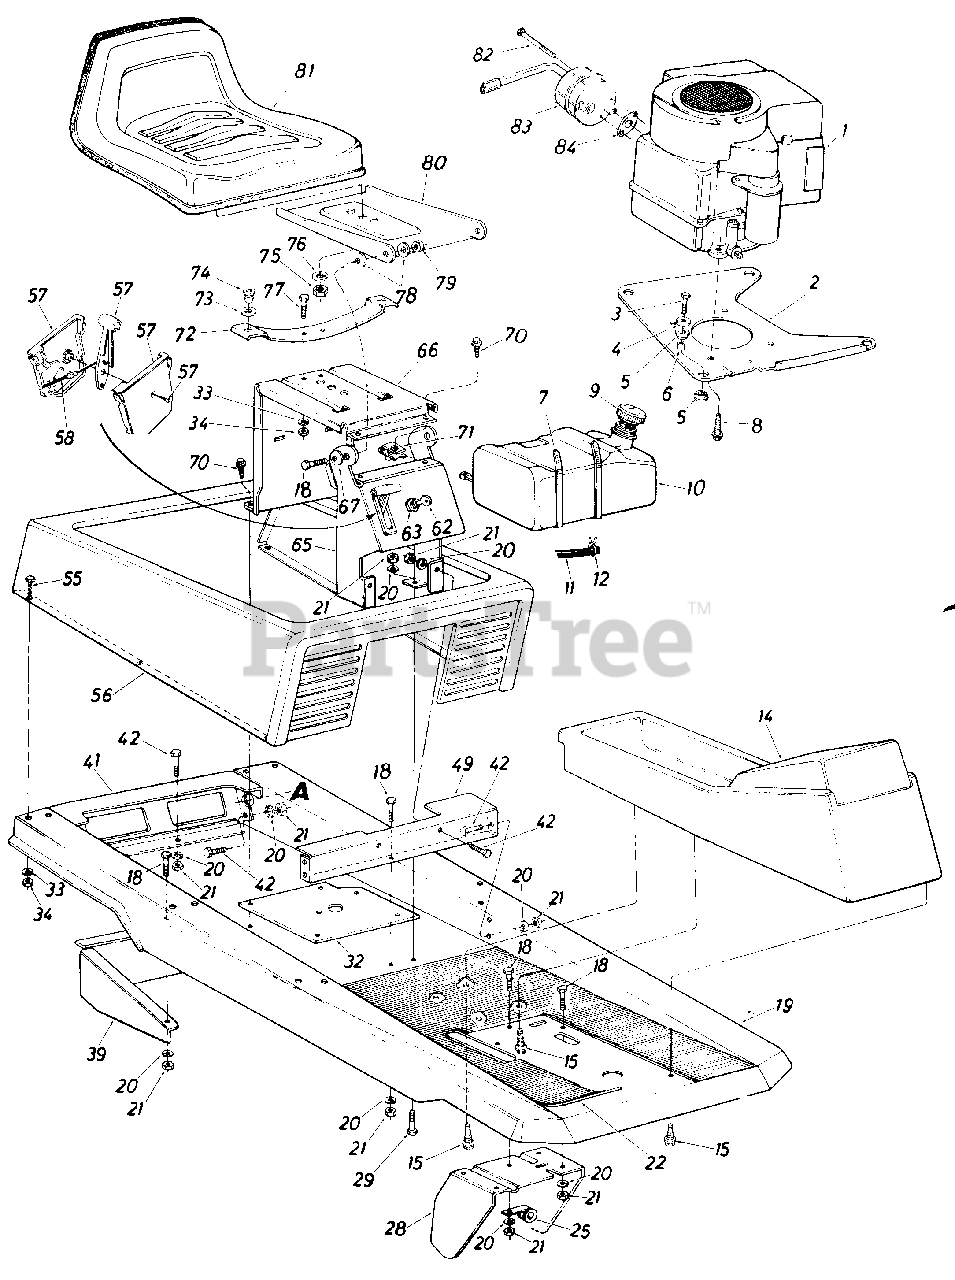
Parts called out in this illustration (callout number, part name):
1	Engine
2	Engine Mounting Plate
3	Hex Bolt 5/16-24 x 1.25" Lg.
4	Fl-Wash. .330" I.D. x 1.125" O.D.
5	Engine Mounting Grommet
6	Spacer.315" I.D. x .50" O.D. x .520" Lg.
7	Cable Tie
8	Hex Wash. Hd. Self-Tap Scr. 3/8-16 x 1.25" Lg.
9	Gas Gauge
10	Fuel Tank
11	Gas Line
12	Hose Clamp .406" Dia.
14	Front Console
15	Plastite Scr. 5/16" x 1.25" Lg.
18	Hex Bolt 5/16-18 x .75" Lg.*
19	Main Frame
20	L-Wash. 5/16" I.D.
21	Hex Nut 5/16-18 Thd.
22	Floor Mat
25	Clamp
28	Clutch-Brake Pedal Ass'y.
29	Hex Bolt 5/16-18 x .62" Lg
32	Mounting Brk't. Variable Speed Pulley
33	L-Wash. 1/4" I.D.
34	Hex Nut 1/4-20 Thd.
49	Seat Support & Frame Brk't.
55	Hex Bolt 1/4-20 x .50" Lg.
56	Engine Cover Ass'y.
57	Throttle Control Box Ass'y.
58	Throttle Control Wire
62	Ignition Key
63	Ignition Switch
65	Front Seat Bracket
66	Rear Seat Bracket
67	Bell-Wash. .345" I.D. x .88" O.D.
70	Hex Wash Hd. Scr. 5/16-18 x .75"
71	Palnut Lug 5/16-18 Thd.
72	Seat Spring
73	Fl-Wash. .531" I.D. x .930" O.D.
74	Grommet
75	Hex Nut 1/2-13 Thd.
76	L-Wash. 1/2" I.D.
77	Hex Bolt 1/4-20 x .62" Lg.
78	Bell-Wash. .345" I.D. x .88" O.D.
79	Hex Cent. L-Nut 5/16-18 Thd.
80	Seat Pivot Bracket
81	Seat Ass'y. Comp.
82	Shld. Bolt
83	Muffler Ass'y.
84	Exhaust Gasket
